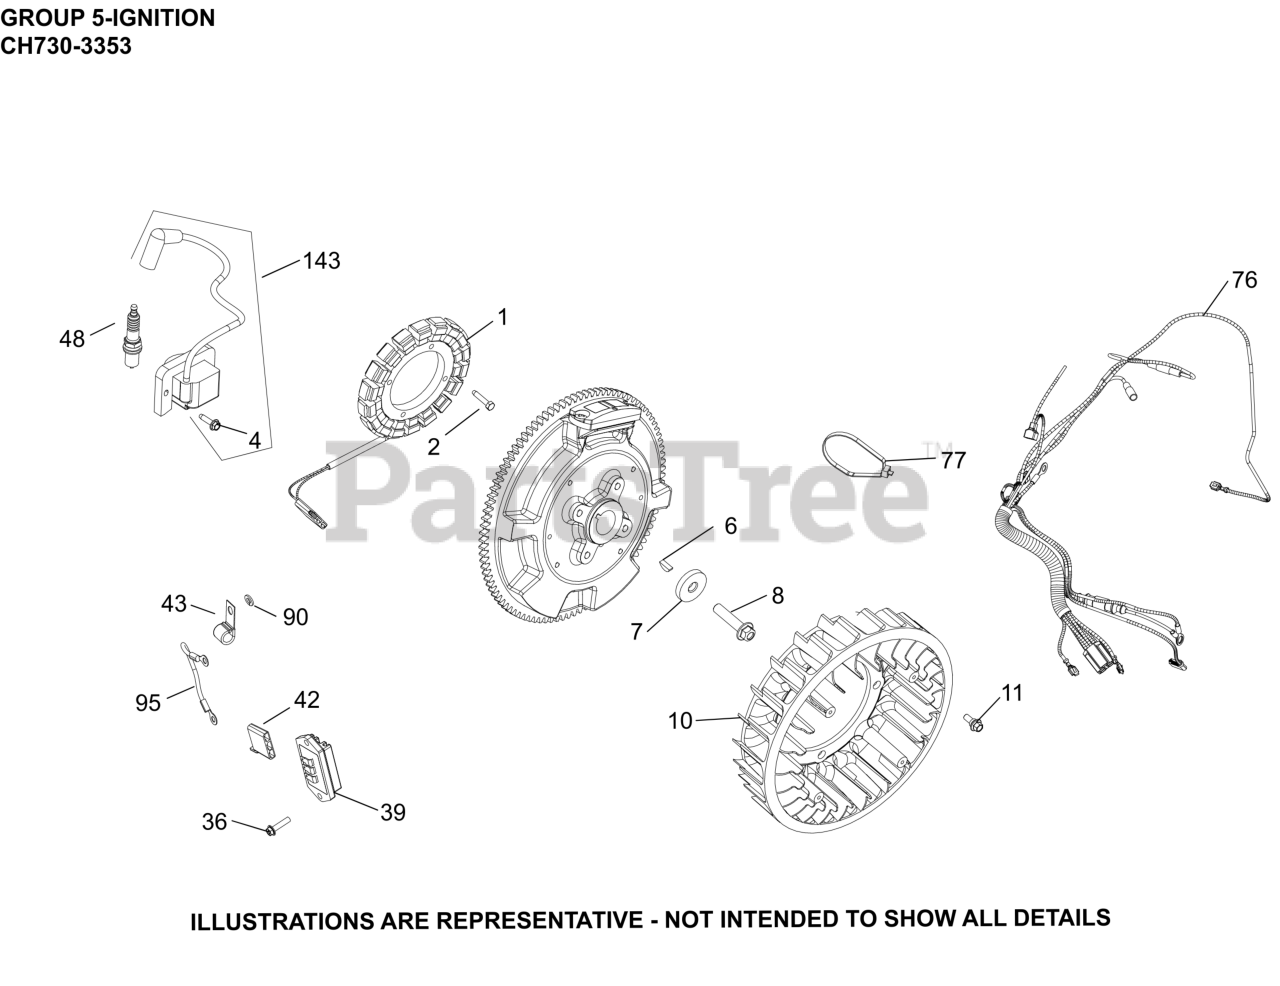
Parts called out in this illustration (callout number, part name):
1	KIT, 15 / 20 AMP STATOR
2	SCREW, THREAD FORMING
4	SCREW, THREAD FORMING
6	KEY, 3/16" X 5/8"
7	WASHER, FLAT
8	SCREW, HEX FLANGE
10	FAN-USE 24 755 253-S
11	BOLT, SHOULDER
36	SCREW, HEX FLANGE HI-LO
39	REGULATOR/RECT 12/15A-(#2540345S)
42	CONNECTOR
43	CLIP, CABLE
48	PLUG, SPARK (STD)
76	HARNESS, WIRING
90	WASHER, LOCK
143	KIT IGNITION MODULE
NI	FLYWHEEL ASSEMBLY (CV/CH670 & 730)
